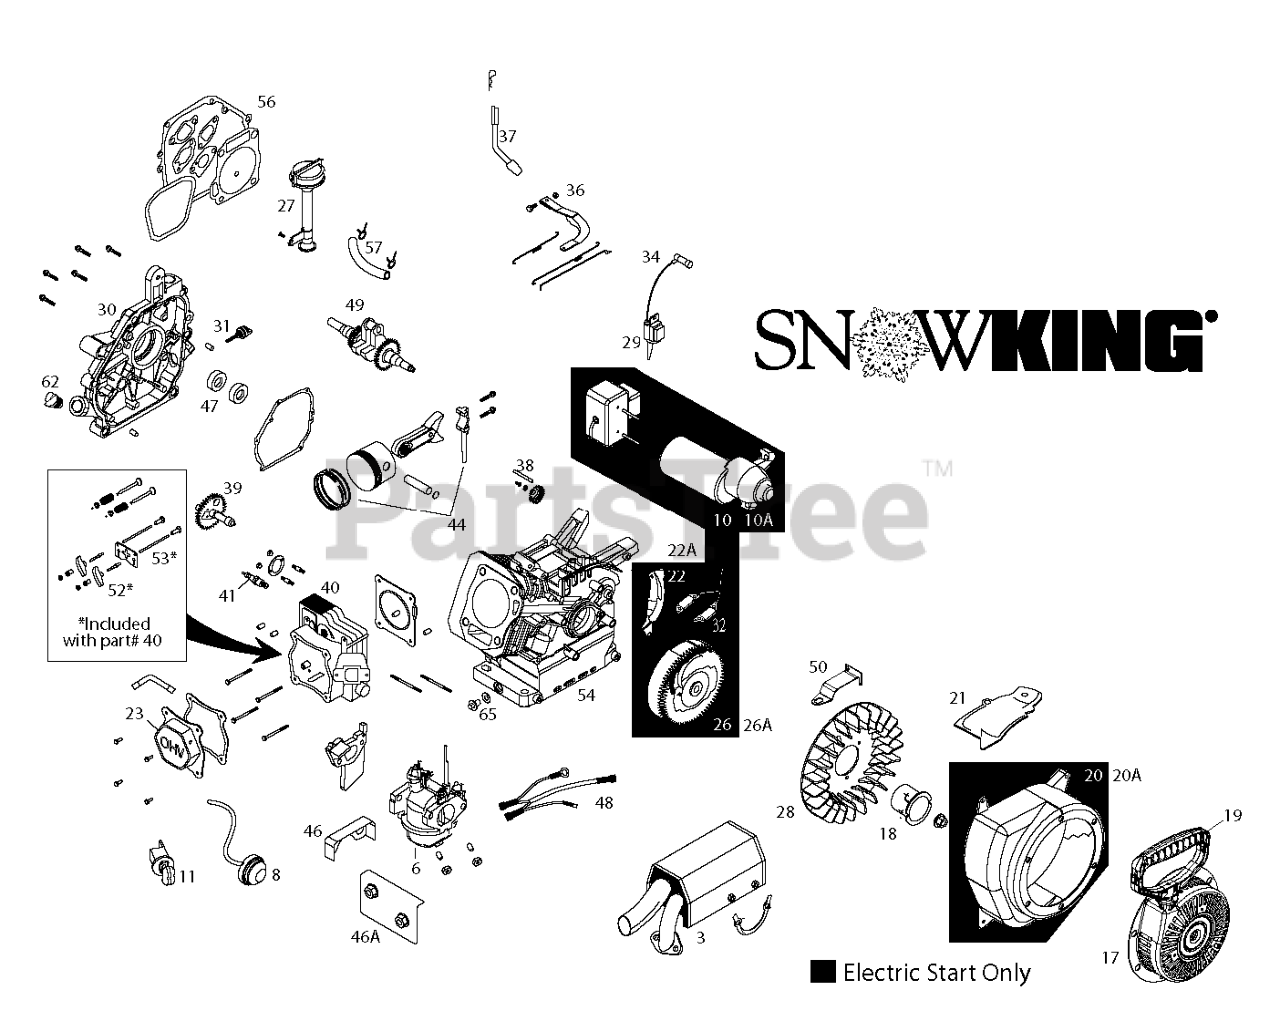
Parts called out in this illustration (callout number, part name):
3	MUFFLER.ASM.LCT.208CC.SNGL.STG
6	CARB.ASM.SS/SNO.LCT(SKSNO313)
8	BULB.FUEL.PRMR.W/HOSE(SKSNO306
10	STARTER.ASM.ELEC.(SKSNO411)
10A	STARTER STARTER.EURO
11	SWITH.KEY.ASSEM.SNOW.SINGLE.ST
17	RECOIL.STRT.ROUND(BLK) SNOW
18	STRTER.CUP(NON-SLOT)SKSN0601.2
19	HANDLE.RECOIL.DELUXE.LCT
20	BLOW.HSG.ASSY.ELEC(SKSN-0602)
20A	BLOW.HSG.ASSY.ELEC(SKSN-0612)
21	SHILED.FLYWEEL.SYS(SKSN-0604)
22	SHLD.ELEC.START.FLY(SKSN-0605)
22A	SHIELD.FLYWEEL.MAN(SKSN-0607)
23	VALVE COVER ASSEMBLY
26	FLYWHL.ASSY.ELECT.(SKSN0405)
26A	RP KIT.FLYWHEEL.SERVICE
27	HIGH OIL-FILL TUBE ASSY
28	FLYWHEEL FAN 420586
29	COIL.ING.CDI.HI TEMP.SKSNO416.
30	CRANKCASE COVER ASSY
31	DIPSTICK SMALL
32	CHARGING.COILS.18-WATT
34	SPARK.PLUG.BOOT.SNW,SKSN4691.1
36	RP_IT.GOVERNOR.ARM(SUMMER ENG)
37	KIT.GOVERNOR.CRANK(SK208-3100)
38	GOVENOR.GEARS ASM(SK2082900)
39	KIT.CAMSHAFT.208CC.LCT
40	CYLINDR.HEAD.SRV.KIT W/GASKET
41	SPARK.PLUG(2083810)
44	KIT.PISTON.SRV(SK208-1400)
46	SHIELD.VAPOR.SNOW
46A	SHIELD.INTAKE.(LCT.SKSN0140.1)
47	SEAL KIT (2 PCS)
48	HARNESS.WIRE.SINGLE.STAGE.LCT
49	CRANKSHAFT-KEYED(SK2081800.1)
50	SPEED.CTRL.BRKT.(SKSN0150)
52	ROCKER ARM KIT
53	KIT.PUSH.ROD.SRV(SK208-1001)
54	CYLINDER.ASM.SKSN0001.2
56	GASKET.KIT.208CC(SK2084300.1)
57	KIT.FUEL.HOSE.208CC.SING/STAGE
62	NON REMOVABLE PLUG
65	KIT.OIL.DRAIN.PLUG(SK2089911
